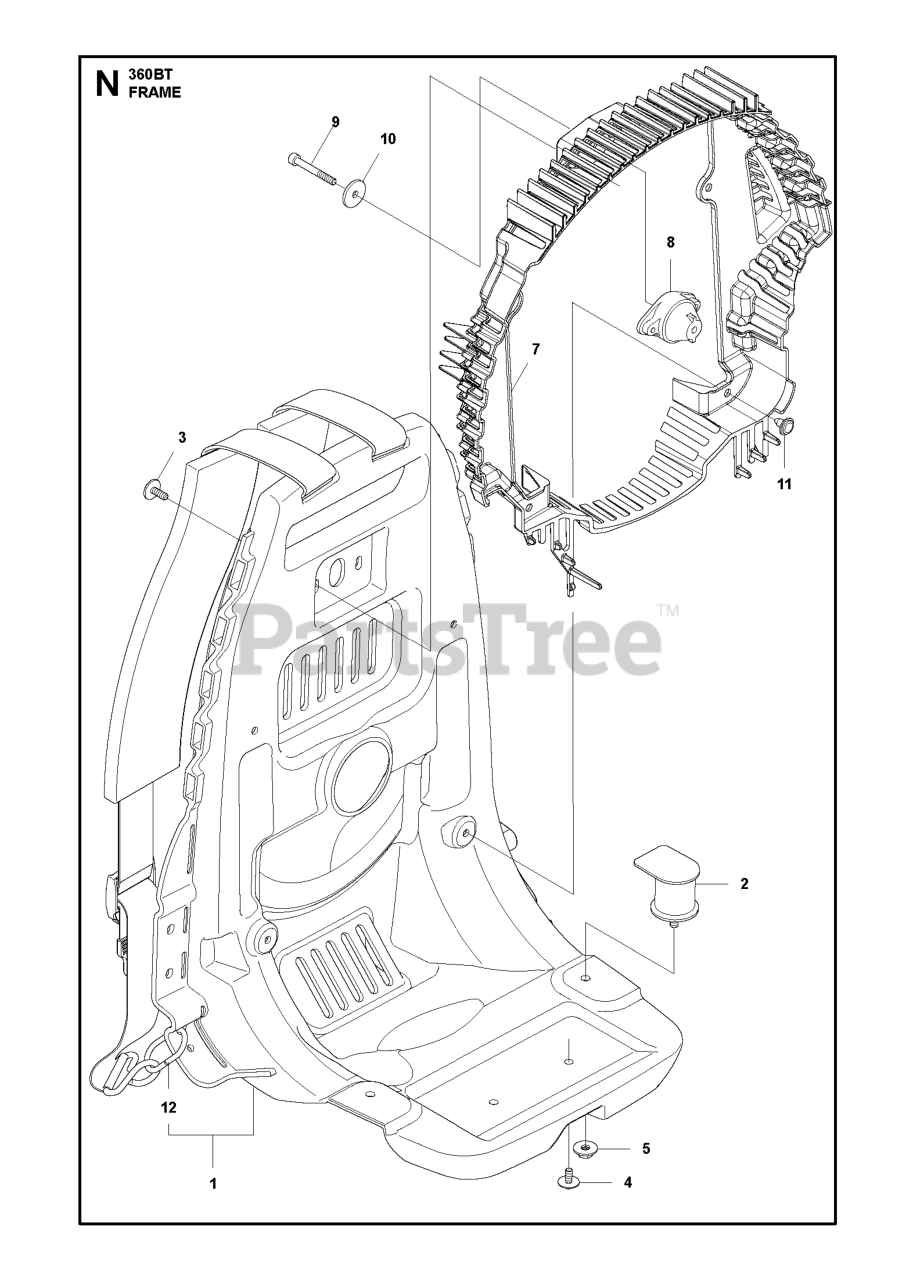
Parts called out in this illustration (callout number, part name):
1	FRAME ASSY
7	NET FREE FLOW
8	DAMPER UPPER
